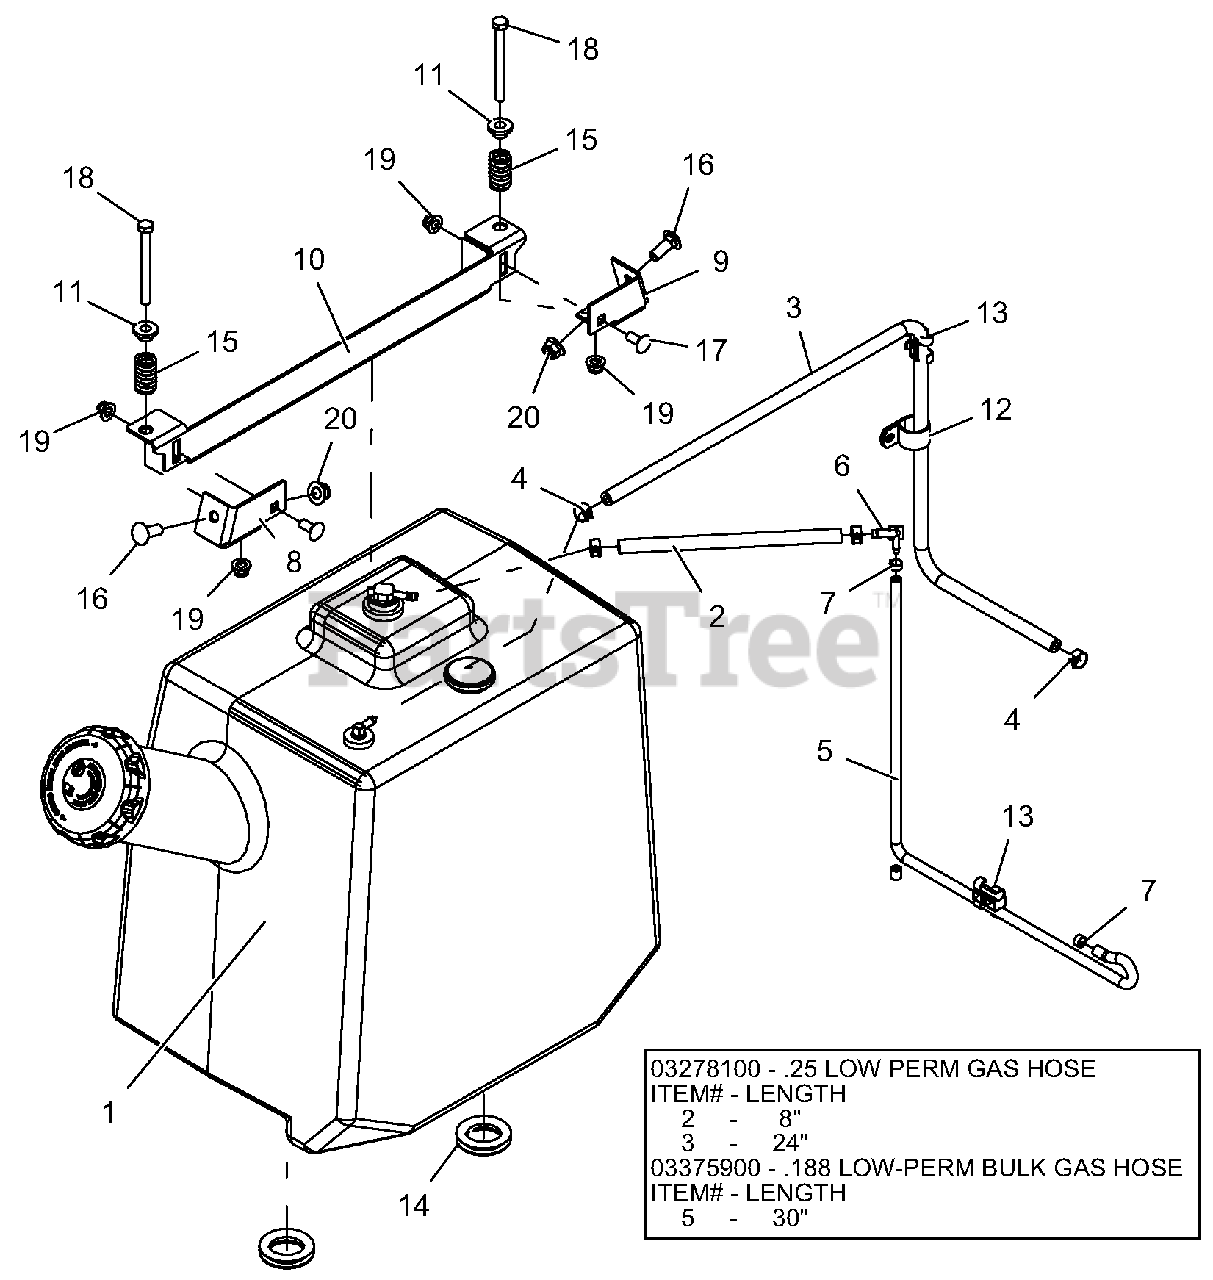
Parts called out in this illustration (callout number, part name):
1	ASSY, EPA PROSTANCE FUEL TANK
2	.25 LOW PERM GAS HOSE
3	.25 LOW PERM GAS HOSE
4	CLAMP, FUEL LINE
5	HOSE, .188 LOW-PERM BULK GAS
6	FITTING - 3/16 x 1/4 90DEGREE VAC
7	CLAMP - HOSE, SPRING .188
8	WLDMT, TANK HOLDDOWN - RH
9	WLDMT, TANK HOLDDOWN - LH
10	HOLDDOWN, FUEL TANK
11	BSHG, FLG .385 x .500 x .875 x .406
12	CLAMP, CUSHIONED STEEL REV
13	CLIP, T, .38-.50
14	GROMMET, 1.25"
15	SPRG, COMPRESSION
16	BLT-RDHDSQNK .38-16 x 1.00 G5 YWZC
17	BLT-RDHDSQNK .31-18 x .75 G5 YWZC
18	BLT-HEX .31-18 x 3.25 GR5 YWZC
19	NUT-LK-NYL-FLG .31-18 YWZC
20	NUT-LK-NYL-FLG .38-16 YWZC
